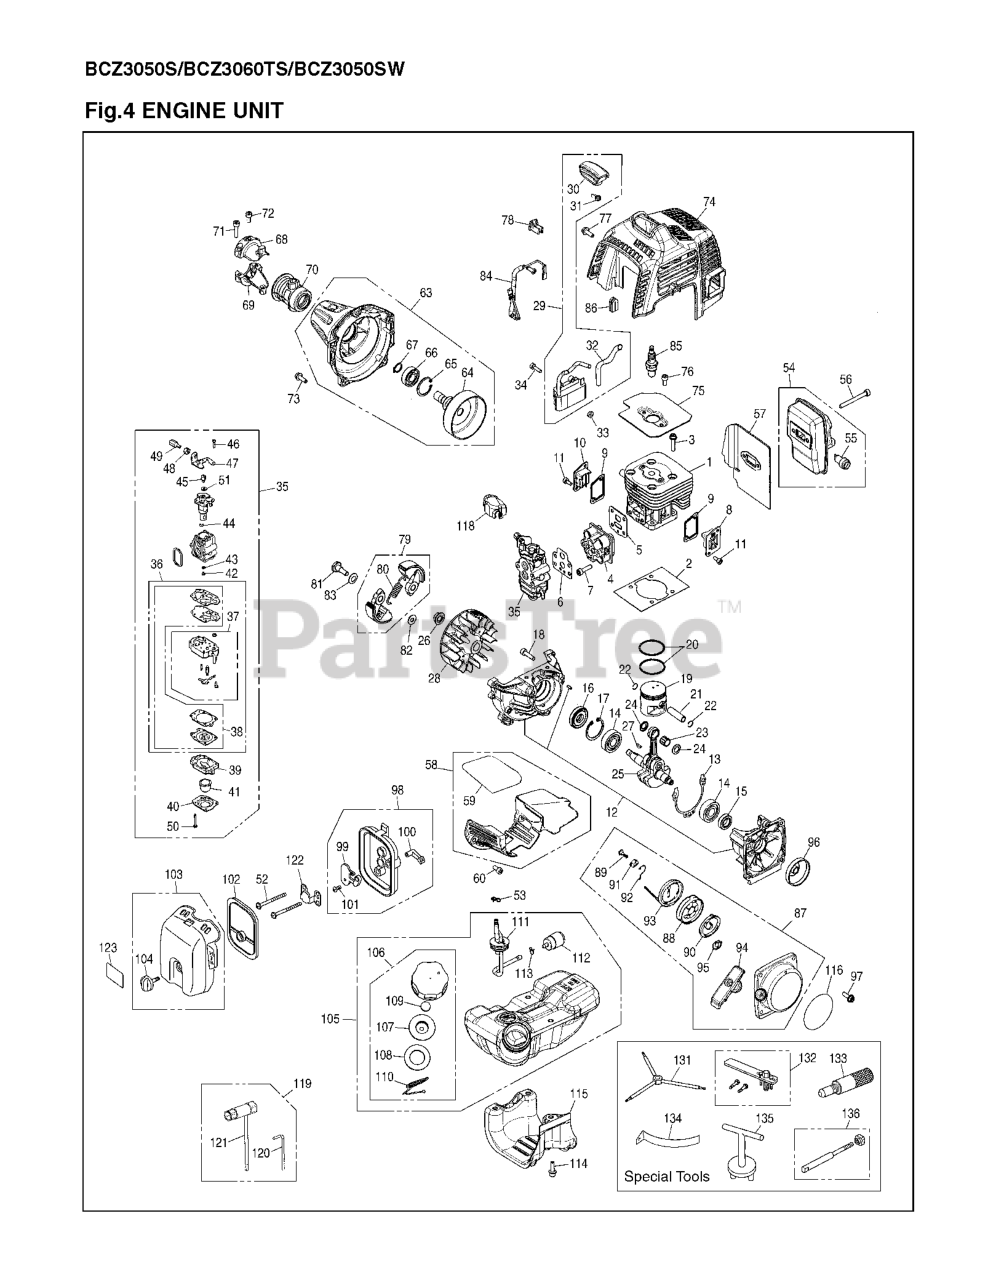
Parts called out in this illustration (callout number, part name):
1	CYLINDER
2	GASKET
3	BOLT
4	INSULATOR
5	GASKET, INSULATOR
6	GASKET, CARB (RPLS T155113131)
7	BOLT, TORX
8	COVER, TRS
9	GASKET, TR
10	COVER,TRF (RPLS 848F6012D1)
11	SCREW
12	CRANKCASE-C
13	GASKET
14	BEARING
15	SEAL
16	SEAL, OIL (RPLS 1200-21220)
18	SCREW
20	RING
21	PIN
22	RING, SNAP
23	BEARING
24	WASHER (RPLS 331041341)
25	CRANKSHAFT-C
26	NUT(RPLS 1140-43230&182301)
27	KEY
29	COIL-A
31	SPRING
32	TUBE (RPLS 261671510,1511)
33	RP_SPACER (RPLS 1260-71260)
34	RP_BOLT TORX
35	CARBURETOR ASSY
36	REBUILD KIT
37	BODY, PUMP
38	GASKET KIT
39	BODY, PURGE
40	RP_COVER, PUMP
41	RP PUMP, PRIMING
42	JET (RPLS 481081250)
43	RING, O
45	RP_SWIVEL
46	RP_SCREW
48	%NUT CABLE 506612601***
49	%ADJUSTER 506613601***
50	SCREW
51	WASHER
52	CABLE THROTTLE MC9114310002
53	CLIP
54	MUFFLER ASSY
55	ARRESTER
56	BOLT
57	GASKET
58	PLATE-A
60	BOLT
63	HOUSING ASSY
64	DRUM (RPLS 481031120-22)
68	BRACKET (A) (RPLS T170031211)
69	BRACKET (B)
70	CUSHION (RPLS T170031231)
71	SCREW
72	BOLT
73	BOLT
74	COVER, ENGINE
75	RP_PLATE
76	BOLT
77	BOLT, TORX
78	CLAMP
79	SHOE
80	SPRING
81	BOLT
82	WASHER
83	WASHER (RPLS 1140-51241)
84	CORD COMP.
85	SPARK PLUG CMR7H-10
86	GROMMET
87	RECOIL-A
88	REEL
89	SCREW
90	SPRING, SPIRAL
91	COLLAR
92	ARM
93	ROPE (RPLS 450075160)
94	KNOB (RPLS 3330-75420)
95	PLATE, STOPPER
96	PULLEY
97	BOLT, TORX
98	CLEANER BODY ASSY
99	PLATE, CHOKE
101	SCREW
102	ELEMENT
103	CAUTION LAEL
104	Cleaner Knob
105	TANK(EVAPO)
106	CAP ASSY
107	HOLDER (RPLS 450085230)
108	RP_PACKING
109	FILTER
110	STOPPER***
111	PIPE-C
112	FILTER
113	CLIP
114	BOLT
115	GUARD, TANK
116	LABEL, RECOIL
118	COVER
119	TOOL SET
120	BAR
123	LABEL
131	WRENCH (RPLS 267096410)
132	PULLER ASSY(R1075-,1140-,1600-
133	STOPPER (TOOL)
134	GAUGE, AIR GAP (TOOL)
135	PULLER, RECOIL (TOOL)
136	ROD-A
